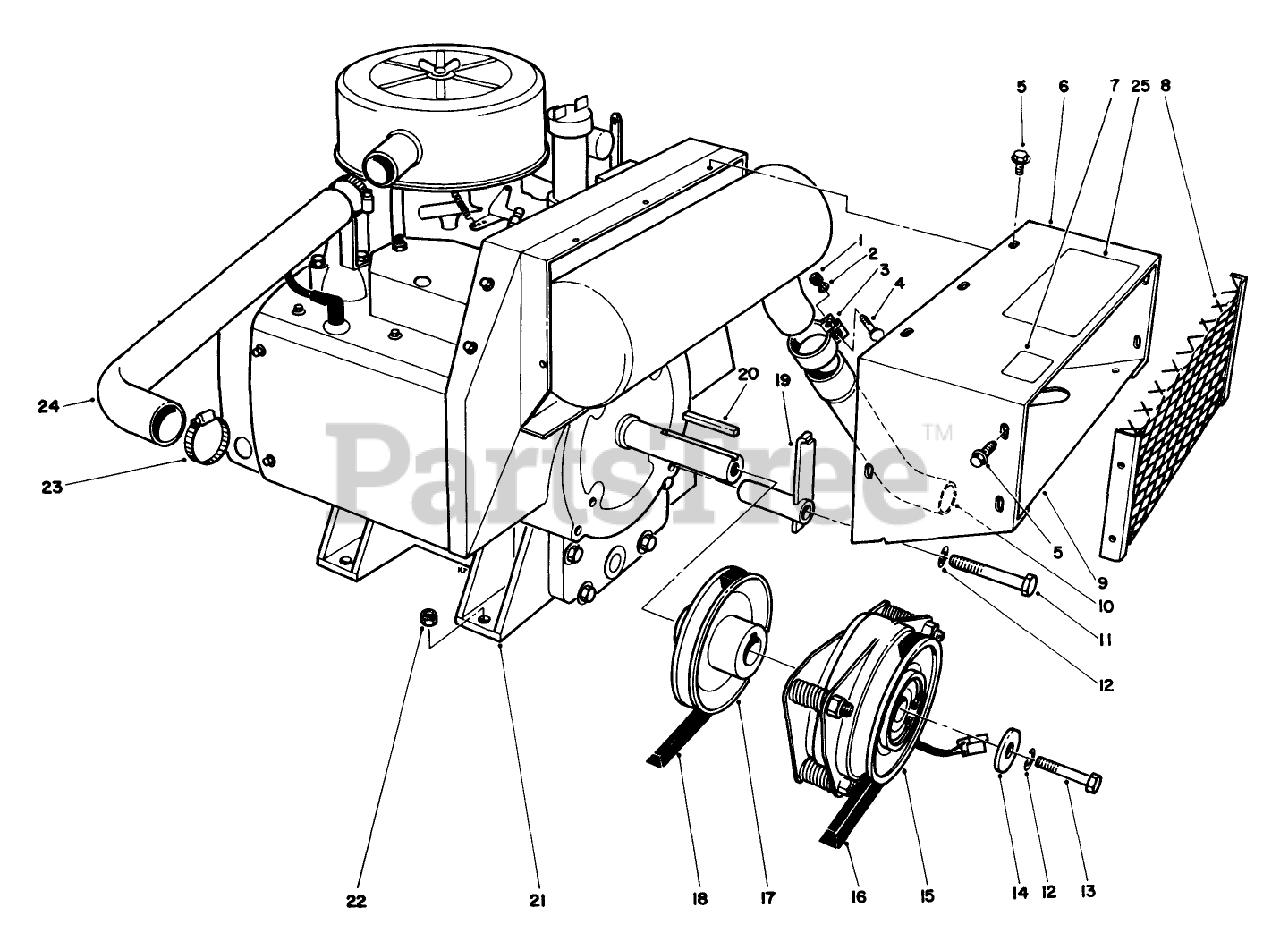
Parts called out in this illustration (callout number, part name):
1	NUT-HEX
2	WASHER-LOCK
3	Clamp (Incl. Ref. #1-2 & 4)
4	SCREW-CARR
5	SCREW-HHFTF
6	ENGINE DUCT WA B
7	Decal-Hot
8	Screen
9	BOTTOM DUCT B
10	EXHAUST PIPE
11	SCREW-HH
12	WASHER-LOCK
13	SCREW-HH
14	WASHER-CLUTCH
15	BRAKE CLUTCH ASM
16	V-BELT, JACKSHAFT
17	ENGINE PULLEY
18	V-BELT, TRACTION
19	Anchor Bracket
21	Engine
22	NUT-LOCK, NI
23	CLAMP-HOSE
24	AIR CLEANER HOSE
25	DECAL - SERVICE INSTR.
